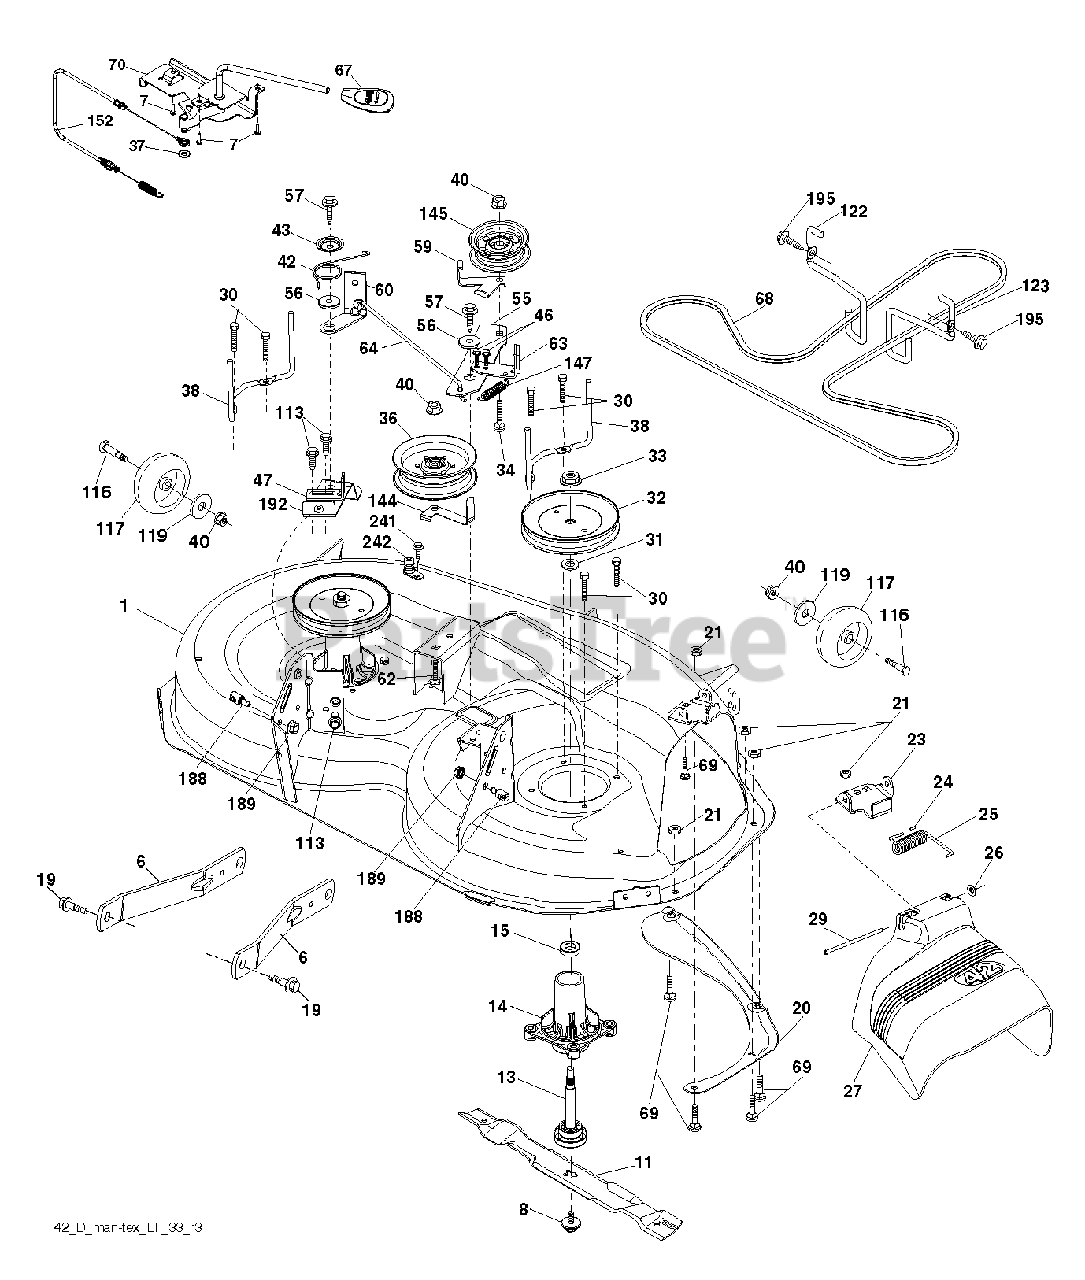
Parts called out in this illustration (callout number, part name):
1	DECK.WELDMENT.42"PAINT
6	ARM.SUSPENSION.MOWER.R
7	SCREW.#10 X 0.750.BOS
8	BOLT.WASHER.ASM.7/16-2
11	42" HI-LIFT BLADE
13	SHAFT.ASM.MDRL.N/GREASE.38
14	HOUSING.MANDREL.4PT.
19	BOLT.SHOULDER
20	BAFFLE.VORTEX
21	LOCKNUT
23	BRKT.DEFLECTOR.38"2005+
24	CAP-SLEEVE LT
25	SPRING.TORSION.DEFLECT
26	NUT PUSH M
27	SHIELD.DEFLECTOR.MOWER.42"BLAC
29	ROD.HINGE
30	SCREW, WASHER HEAD
31	WASHER.SPACER.MANDREL
32	PULLEY.MANDREL.5.438.PD
33	NUT.FLANGE.LOCK.TOP
34	BOLT.3/8-16X1.50
36	PULLEY.IDLER.2006
37	WASHER
38	KEEPER.BELT.LH.MANDREL
40	NUT LOCK FLG 3/8-16 UNC
42	SPRING.TORSION.BRAKE
43	SRPING.TORSION.RETAINE
46	SCREW.1/4-20X5/8
47	BRKT.CLUTCH.CABLE
55	IDLER.ARM.42"
56	SPACER.RETAINER
57	SCREW 3/8-16X1
59	GUARD, BELT
60	ARM BRAKE MOWER
63	ARM BRAKE MOWER
64	LINK BRAKE
67	HANDLE.CLUTCH.CABLE.LT
68	BELT.DECK.DRIVE.42"
69	BOLT
70	CLUTCH.ASM.CABLE.HUSQ.TEX
113	BOLT.5/16HEX.WHS.HD
116	BOLT.SHOULDER.3/8-16X3-5/8.
117	WHEEL. GUAGE RALLY
119	WASHER
122	KEEPER BELT ENGINE LH
123	KEEPER BELT RH
144	KEEPER.BELT.MOWER
145	PULLEY.IDLER.48"PRIMARY
147	RETURN SPRING
152	CABLE CLUTCH MANUAL W/SPR.
188	STUD.FASTNER.W/ANTI-ROTATE
189	NUT LOCK HEX FLANGE 5/16-18
192	BRKT.BRAKE.STAND.LH.
195	SCREW, 3/8-16X3/4
241	SCREW.TT.#10-32X.5.3/8.FLANGE
242	PORT.WASHOUT
